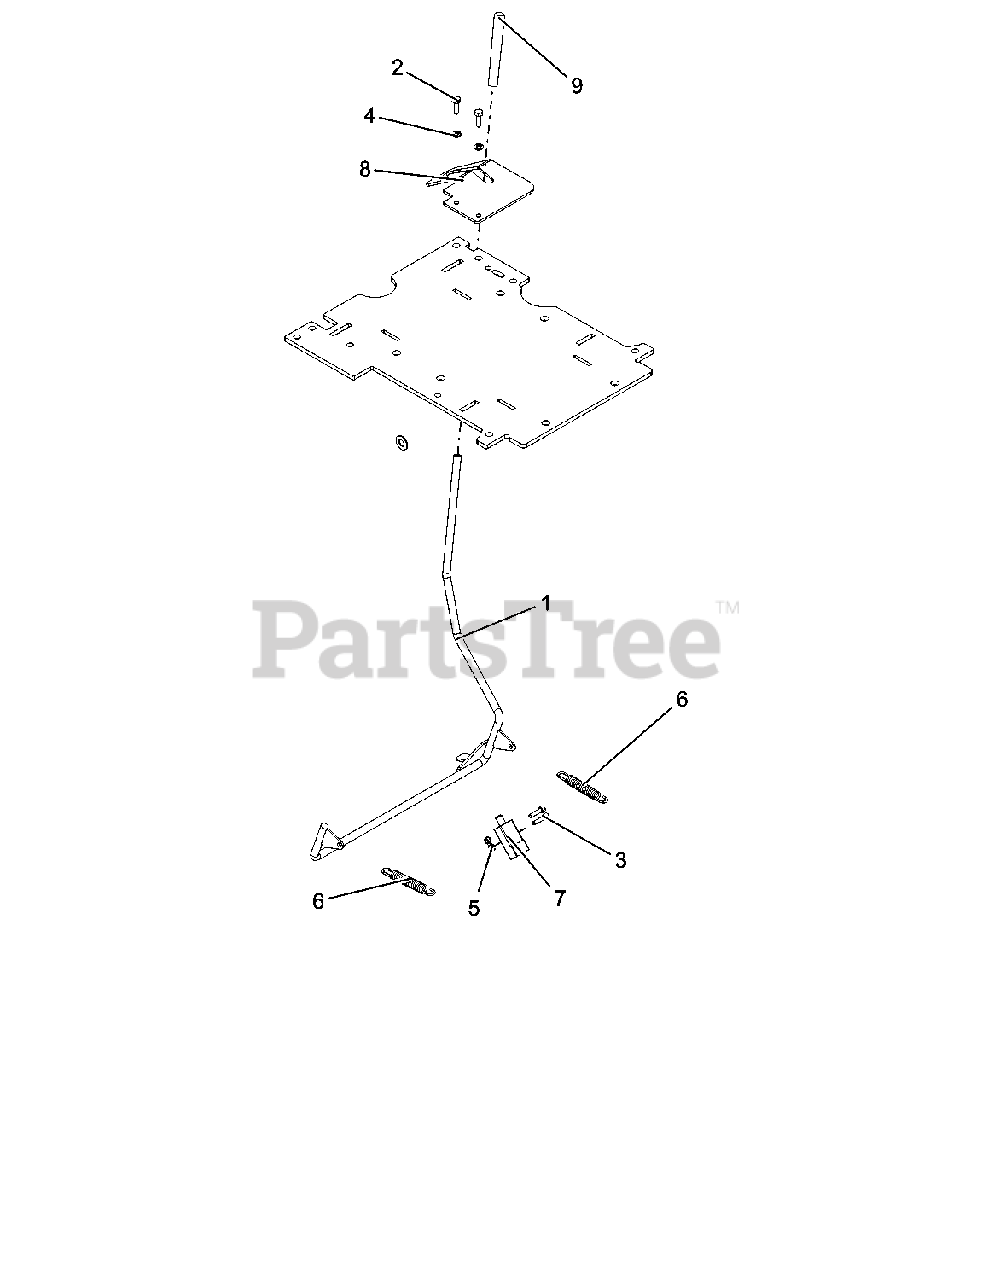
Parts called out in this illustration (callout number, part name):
1	WLDMT, LEVER BRAKE-BLACK
2	BLT, HEX M6-1X20 GR8.8 ZC120
3	SCR, SKH M5-.8 X 20 GR12.9 ROHS
4	WSHR-LK .25X.062 REG YWZC
5	NUT-KEPS M5-.8 GR8.8 ZC120
6	SPRG, EXTENSION .0945X.503X3.150
7	SWITCH, INTERLOCK REV C
8	PLATE, BRAKE PROFILE-RED
9	GRIP, PLASTIC
